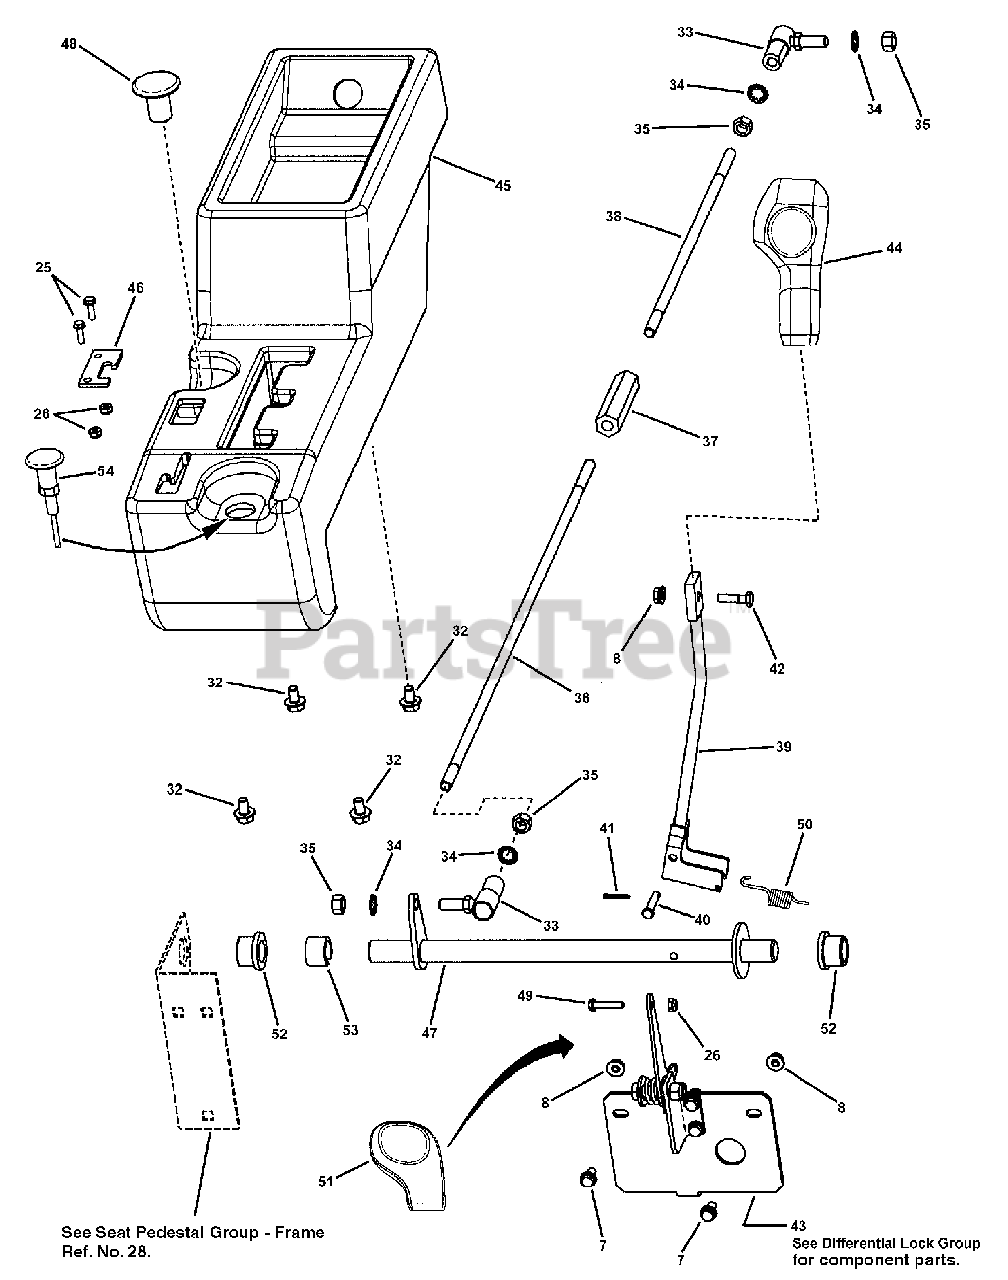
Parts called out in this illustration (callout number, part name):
7	SCREW, Hex Flange Lock, 1/4-20 x 1/2 GR 5
8	NUT, Hex Flange Lock, 1/4-20 GR 5
25	SCREW, Hex Washer Head Machine, #10-32 x 5/8
26	NUT, Hex Nyloc, #10-32
32	BOLT, Hex Flange Lock, 5/16-18 x 1/2
33	BALL JOINT, 3/8-24 Thread
34	WASHER, 3/8 Internal Tooth Lock
35	NUT, Hex, 3/8-24 GR B
36	ROD, CVT Shift, 21-5/8 Long (3/8-24 thread, both ends)
37	HEX BLOCK, Shift Adj. (3/8-24 thread, LH & RH)
38	ROD, CVT Shift, 12-1/8 Long (3/8-24 thread, LH & RH)
39	ROD ASSEMBLY, Shift
40	CLEVIS PIN, 1/4 x 1-1/4
41	COTTER PIN, 3/32 x 3/4
42	CAPSCREW, Hex Head, 1/4-20 x 1 GR 5
43	DIFFERENTIAL LOCK ASSEMBLY, Used on Turf Cruiser Models 85632 & 85668 (See Differential Lock Group for component parts.)
43	DIFFERENTIAL LOCK ASSEMBLY, Used on Trail Cruiser Model 85903 (See Differential Lock Group for component parts.)
44	HANDLE, Shift
45	CONSOLE, UV-2
46	CONTACT PLATE, Differential Lock
47	SHIFTER, Transmission (weldment)
48	KNOB, Park Brake, Red, Used on Turf Cruiser Models 85632 & 85668
48	KNOB, Parking, Used on Trail Cruiser Model 85903
49	SCREW, Hex Washer Head Slot, #10 x 1
50	SPRING, Transmission Extension (Short)
51	KNOB, Throttle (Red)
52	BEARING, .750 I.D.
53	RING, Rear Lift Arm, Blue
54	CABLE, Choke, B&S 16HP Vanguard
